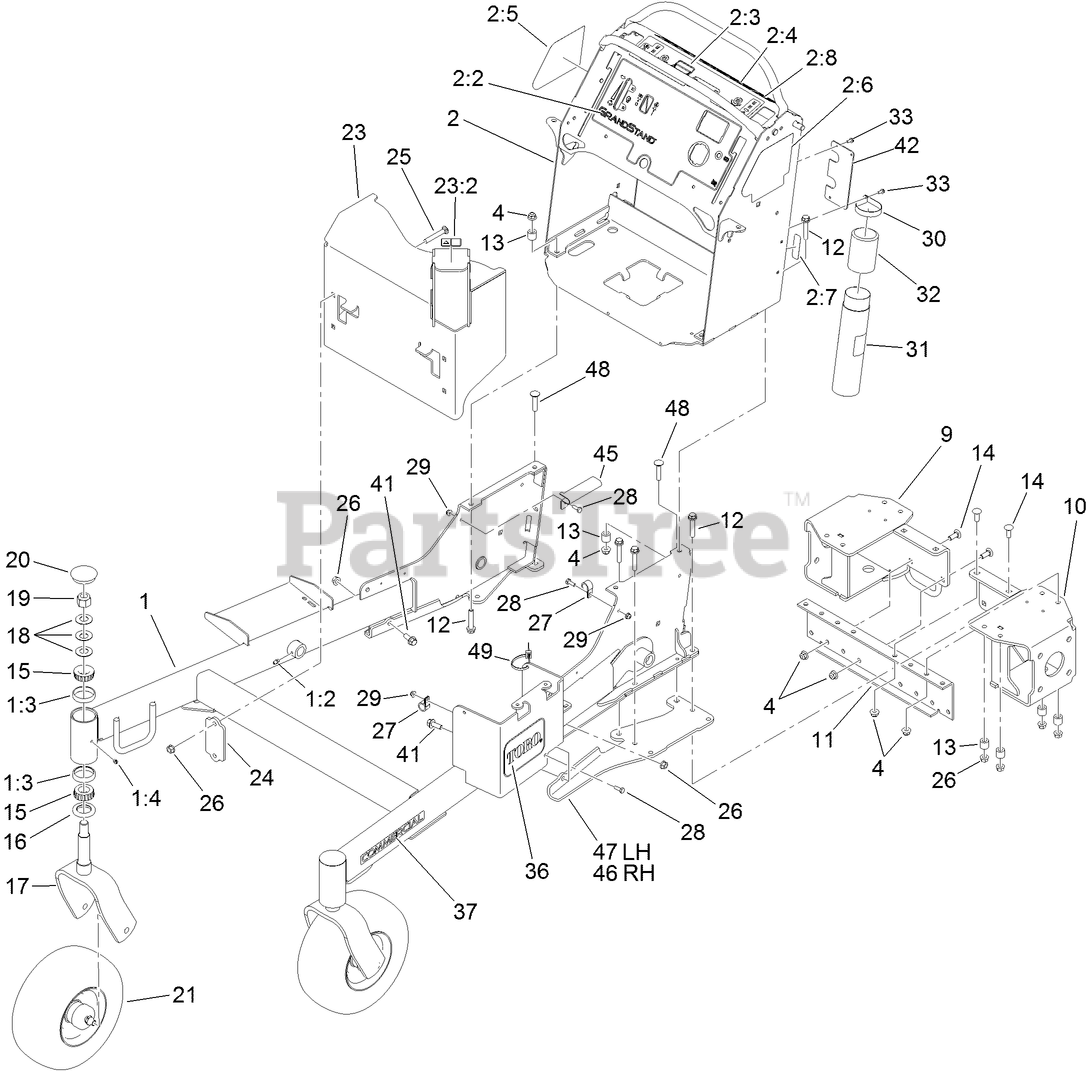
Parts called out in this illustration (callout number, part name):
1	FRONT FRAME ASM
1:2	FITTING-GREASE
1:3	CUP-BEARING
2	CONTROL TOWER ASM
2:2	DECAL-CONTROL PANEL
2:3	DECAL-OPC
2:4	DECAL-WARNING
2:5	DECAL-HOC
2:6	DECAL-SERVICE AID, CE
2:7	DECAL-FUSE
2:8	DECAL-STABILITY, CE
4	NUT-HF, NI
9	MOUNT-MOTOR, RH
10	MOUNT-MOTOR, LH
11	MOUNT-MOTOR, CENTER
12	SCREW-HHF
13	SPACER
14	SCREW-CARR
15	BEARING-ROLLER, TAPERED
16	SEAL-GREASE
17	FORK-CASTER
18	WASHER-BELLVILLE
19	NUT-LOCK, NI
20	CAP-GREASE
21	WHEEL/TIRE AND BEARING ASM
23	MUFFLER GUARD ASM
23:2	DECAL-WARNING
24	BRACKET-MOUNTING, GUARD
25	SCREW-CARR
26	NUT-HF
27	CLAMP-CABLE
28	SCREW-HH
29	NUT-HF
30	CLAMP-R
31	TUBE-MANUAL
32	CAP-HOUSING
33	SCREW-TAPTITE
36	DECAL
37	DECAL-COMMERCIAL
41	SCREW-HHF
42	PLATE-MANUAL
45	BRACKET-HOSE, FUEL (DOUBLE)
46	PLATE-SHIM, RH
47	PLATE-SHIM, LH
48	SCREW-CARR
49	TIE-CABLE
